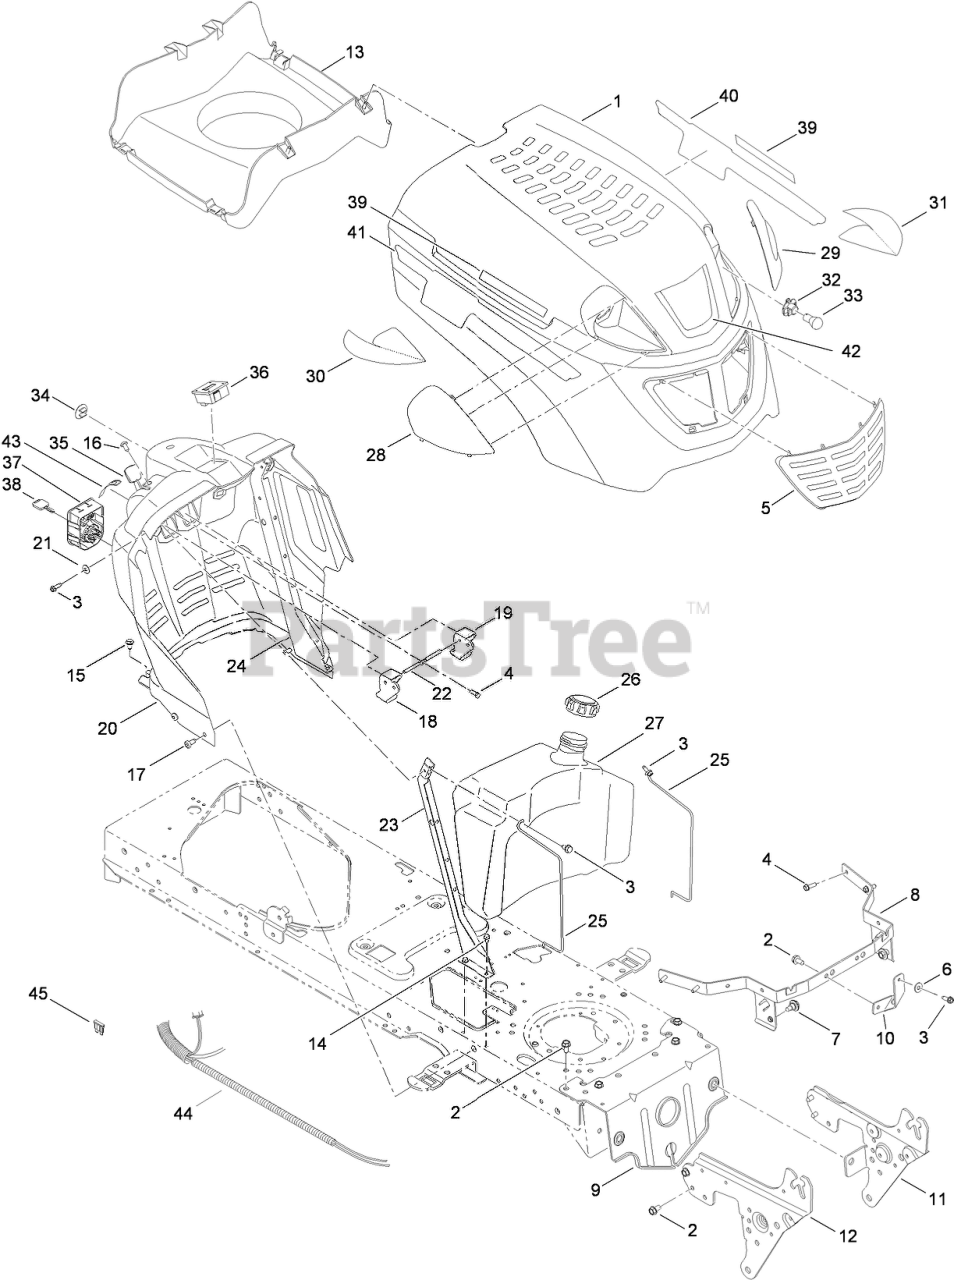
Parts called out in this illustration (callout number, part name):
2	SCREW-TAP
3	SCREW-TAP
4	SCREW-TAP
6	WASHER-FLAT
7	BOLT-SHOULDER, TAP
8	BRACKET-PIVOT
9	BRACKET-PIVOT
10	BRACKET-SUPPORT, HOOD
11	BRACKET-SUPPORT, PIVOT (LH)
12	BRACKET-SUPPORT, PIVOT (RH)
13	PLENIUM-HOOD
14	SCREW-HWHTF
15	SCREW-TAP
16	SCREW-TAP
17	SCREW-TAP
18	LEVER-CRUISE
19	LEVER-BRAKE
20	DASH-MANUAL, PTO
21	WASHER-SPRING
22	ROD-LEVER, BENT
23	SUPPORT-DASH, PLATE (RH)
24	SUPPORT-DASH, PLATE (LH)
25	ROD-SUPPORT
26	CAP-FUEL
27	TANK-FUEL, 3 GAL
28	LENS-RH
29	LENS-LH
30	REFLECTOR-RH
31	REFLECTOR-LH
32	SOCKET-HEADLIGHT
33	LAMP-12V, MINIATURE
34	PLUG-CHOKE
35	CABLE-THROTTLE
36	METER-HOUR
37	MODULE-SWITCH, IGNITION
38	KEY-IGNITION
40	DECAL-HOOD, LEFT SIDE
41	DECAL-HOOD, RIGHT SIDE
42	DECAL-HOOD
43	DECAL-THROTTLE
44	HARNESS-WIRING
45	FUSE-20 AMP
